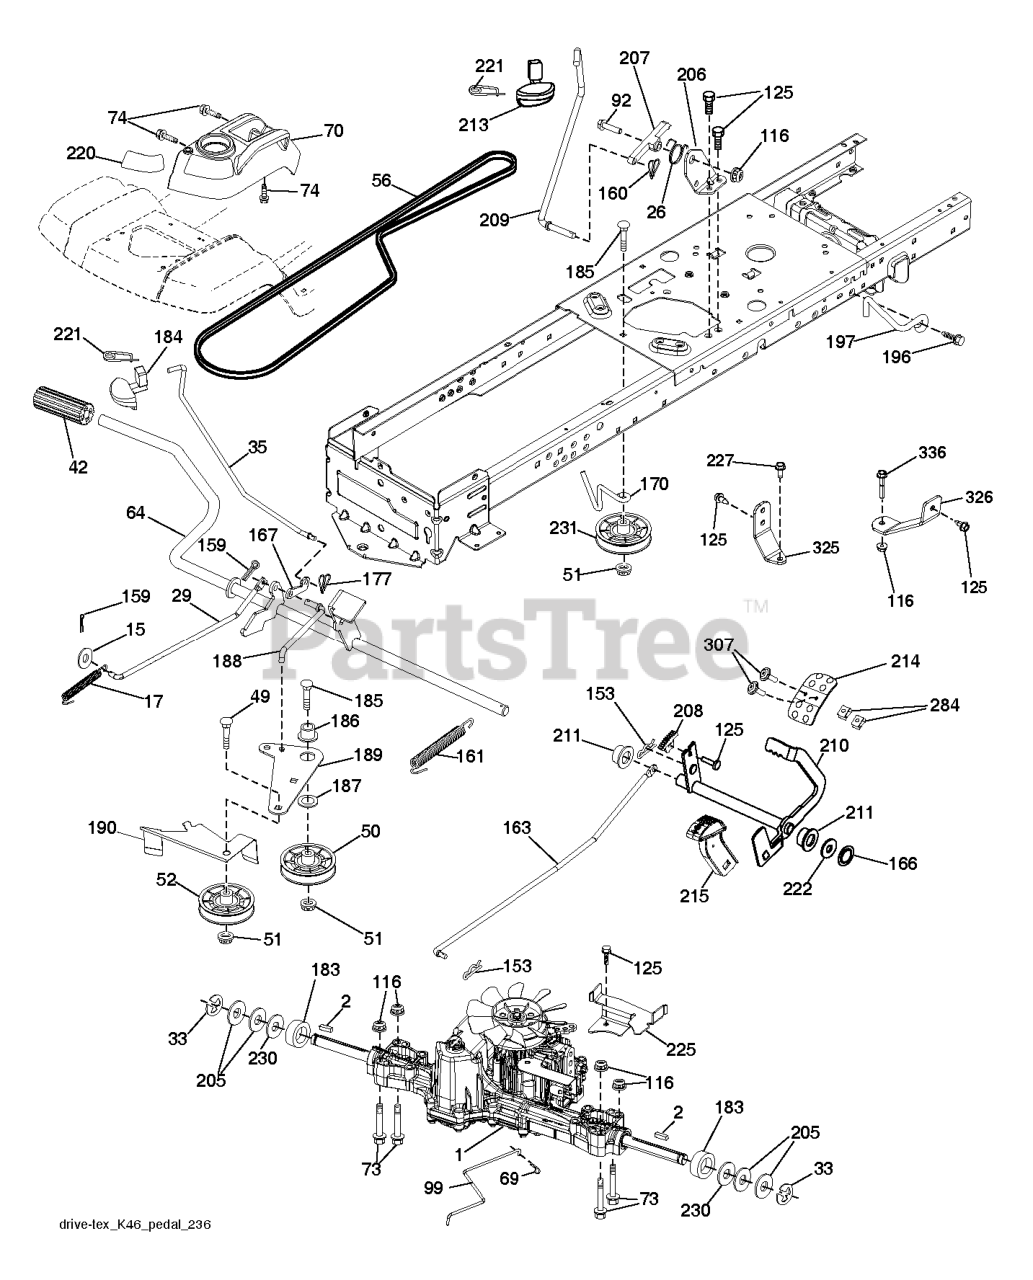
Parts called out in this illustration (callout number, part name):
2	SQUARE KEY
15	WASHER
17	SPRING.BRAKE.K46.GREEN
26	SPRING.RETURN.CRUISE
29	ROD.BRAKE.K46
35	ROD .BRAKE. PARKING. GT. HUSQ.
42	PEDAL COVER T
50	IDLER.FLAT.910.OFFSET
51	NUT LOCK FLG 3/8-16 UNC
52	IDLER.V-GROOVE.910.OFFSET
56	V-BELT.MOWER.92.40.42/K46
64	SHAFT.ASM.PEDAL.BRK.CNTR
69	HAIRPIN.SOFT.ZINC.059X1.125
70	CONSOLE.ASM.RH.GT.FC.HUSQ
73	BOLT
74	SCREW.HI-LO.CONSOLE
92	BOLT
99	ARM.PIVOTING.TCRD.GEN2.5.BAGGE
116	NUT LOCK HEX FLANGE 5/16-18
125	SCREW
153	RETAINER M
159	COTTER PIN
160	RETAINER CLIP
161	SPRING, RETURN LT
163	ROD.CONTROL.K57R.K46
166	NUT.PUSH.625
167	LATCH.BRAKE.SPRING
170	KEEPER.CENTER SPAN.1.688
183	SPACER AXLE
184	HANDLE.PARKING.BRAKE.H (BLK)
186	SPACER.RETAINER
187	WASHER 12/32X2X10GA
188	LINK.CLUTCH.GROUND DRIVE.LONG
189	BELLCRANK.GROUND.DRIVE.TEX.
190	KEEPER.BELLCRANK.DRIVE
196	SCREW 3/8-16X1
197	BRKT.42.FCS.CLUTCH.ANTIROTATIO
206	BRACKET.MOUNT.CRUISE.LATCH
207	LATCH.CONTROL.CRUISE.TEX
208	GEAR.SECTOR.CONTROL.CR
209	ROD.CONTROL.CRUISE.GT.
210	ROCKER.ASM.PEDAL.CONTR
211	BEARING.NYLON
213	KNOB.CONTROL.CRUSIE.HU
214	PEDAL.FORWARD.HUSQVARNA.DEALER
215	PEDAL.COVER.REVERSE.CRD.X428BK
220	REFLECTOR.RH.TEX GT
221	RETAINER.SPRING.CLIP.H
222	WASHER 21/32 X 1-1/4 X 10 GA.
225	KEEPER.BELT.TRANSAXLE.K46
227	SCREW.THDROL.5/16-18X3/4.TTY
230	WASHER.HARDENED
231	IDLER.V-GROOVE.1.688.OFFSET
284	NUT.U-CHNL.1/4-20.550DP.350PNL
307	SCREW.MACHINE.CR.1/4-20
325	TORQUE.STRAP.K46.LT.LH
326	BRCKT.PNT.TRQ.STP.46.18TIRE.RH
336	BOLT.5/16-18X1-3/4.FLANGED.HEX
